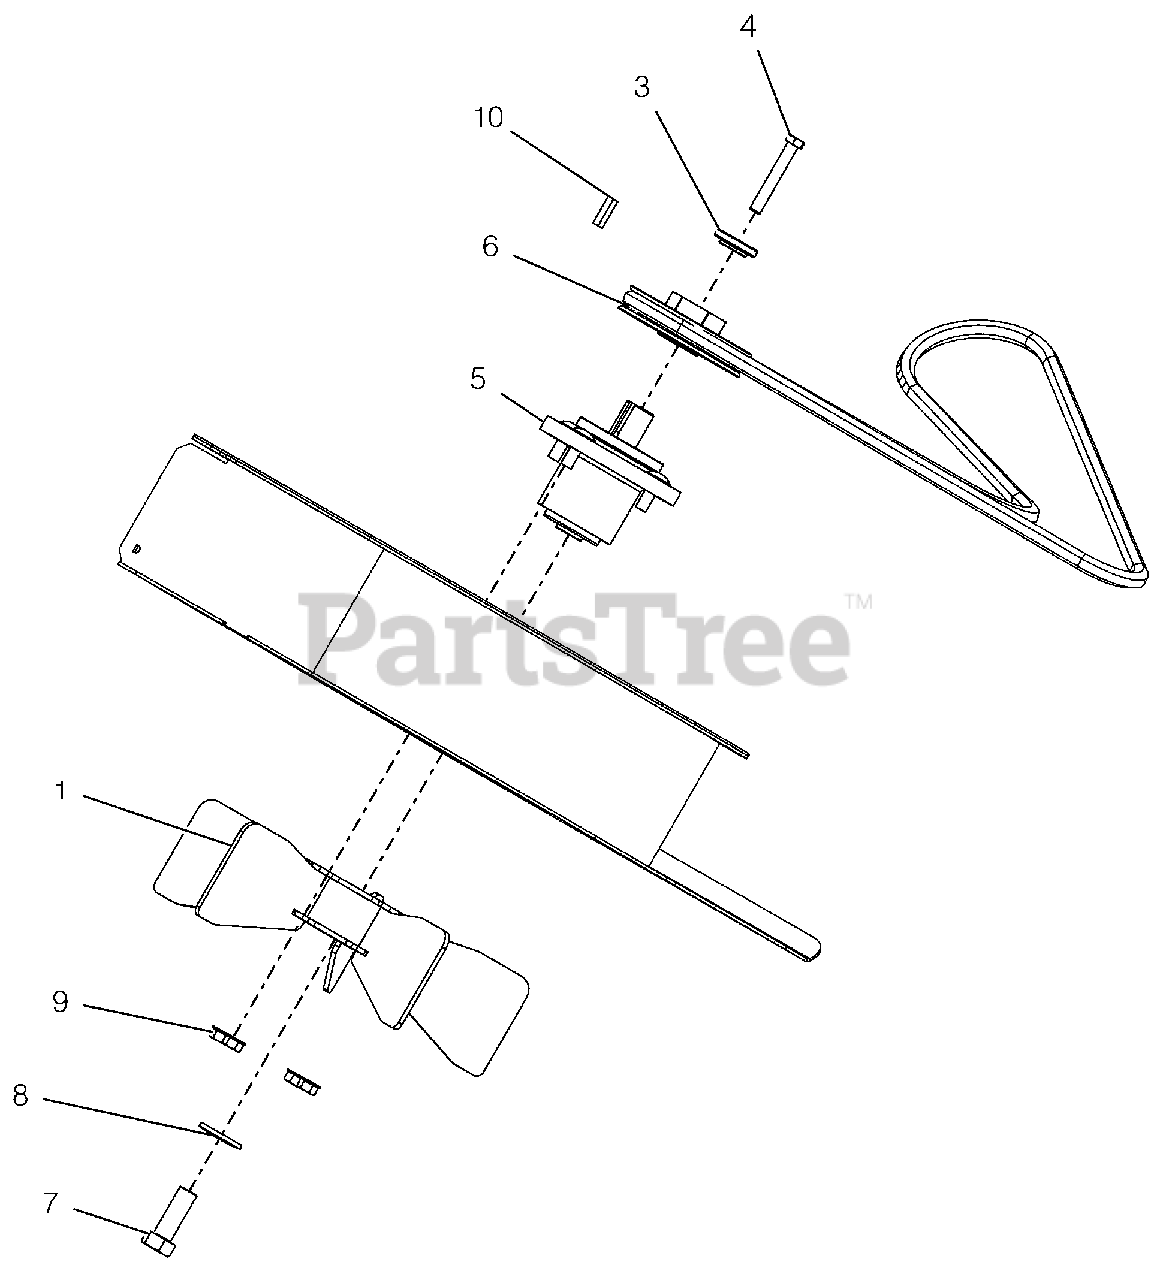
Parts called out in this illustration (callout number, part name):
1	IMPELLER, HD BLOWER
3	RETAINER, SHEAVE
4	BLT-HEX .38-16X2.50 GR8 YWZC
5	SPINDLE, ASM HOUSING - ALUM. (BLOWER)
6	PULLEY, V-1.00"ID X 4.50" OD
7	BLT-HEX .62-18X1.75 GR8 YWZC
8	WSHR-BLVL .669X1.535X.138
9	@NUT-LK-TOP-FLG .38-16 YWZC
10	KEY, SQ .25X.25X1.00 RC 40-50
